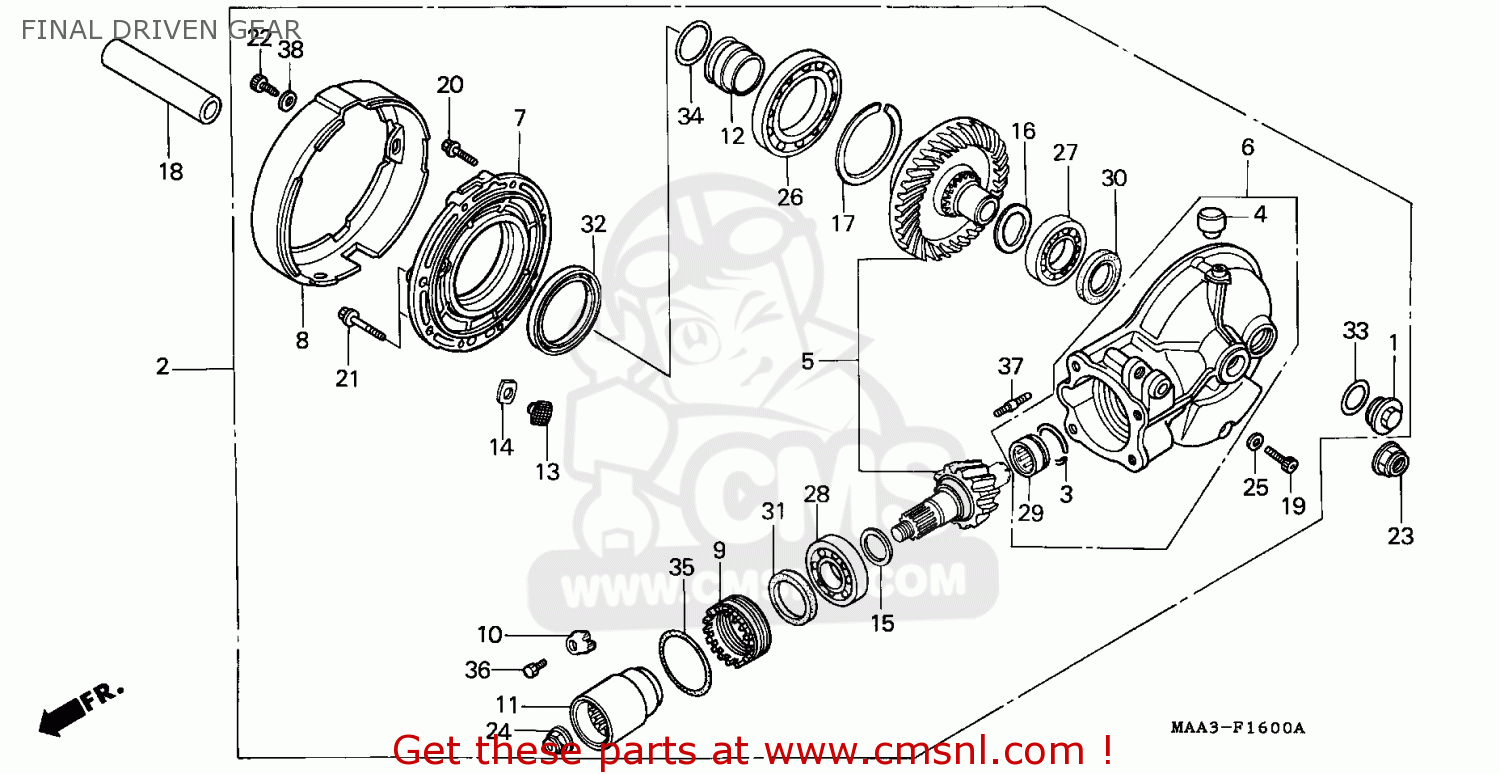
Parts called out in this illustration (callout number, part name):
1	CAP, TAPPET
2	GEAR ASSY,FINAL
3	RING,STOPPER
4	CAP,BREATHER
5	GEAR SET,FINAL
6	CASE SET,FINAL
7	COVER,GEAR CASE
8	PLATE,DUST GUARD
9	RETAINER,BEARING
10	LOCK A BEARING AD
11	JOINT,PINION
12	HOLDER,O-RING
13	PIN,RING STOPPER
14	SHIM A,STOP,PIN
15	SHIM A,PINION GEA
16	WASHER,SPECIAL,
17	SPACER.A.RINGGEAR
18	COLLAR B,RR DIST
19	BOLT,SOCKET,8X11
20	BOLT,FLANGE,8X27
21	BOLT,FLANG 10X35
22	BOLT,HEX.,6X16
23	NUT,FLANGE,18MM
24	NUT,HEX,16MM
25	PACKING 8MM
26	B/BRG RAD N/COM
27	B/BRG RAD N/COM
28	B/BRG RAD N/COM
29	NEEDLE BRG
30	OILSEAL,34X50X7
31	OIL SEAL,39X51X7
32	OIL SEAL.60X80X8
33	O RING, 30.8M/M
34	O-RING,35.2X2.4
35	O-RING,58.5X3.5
36	BOLT,HEX.,6X12
37	BOLT,STUD,10X32
